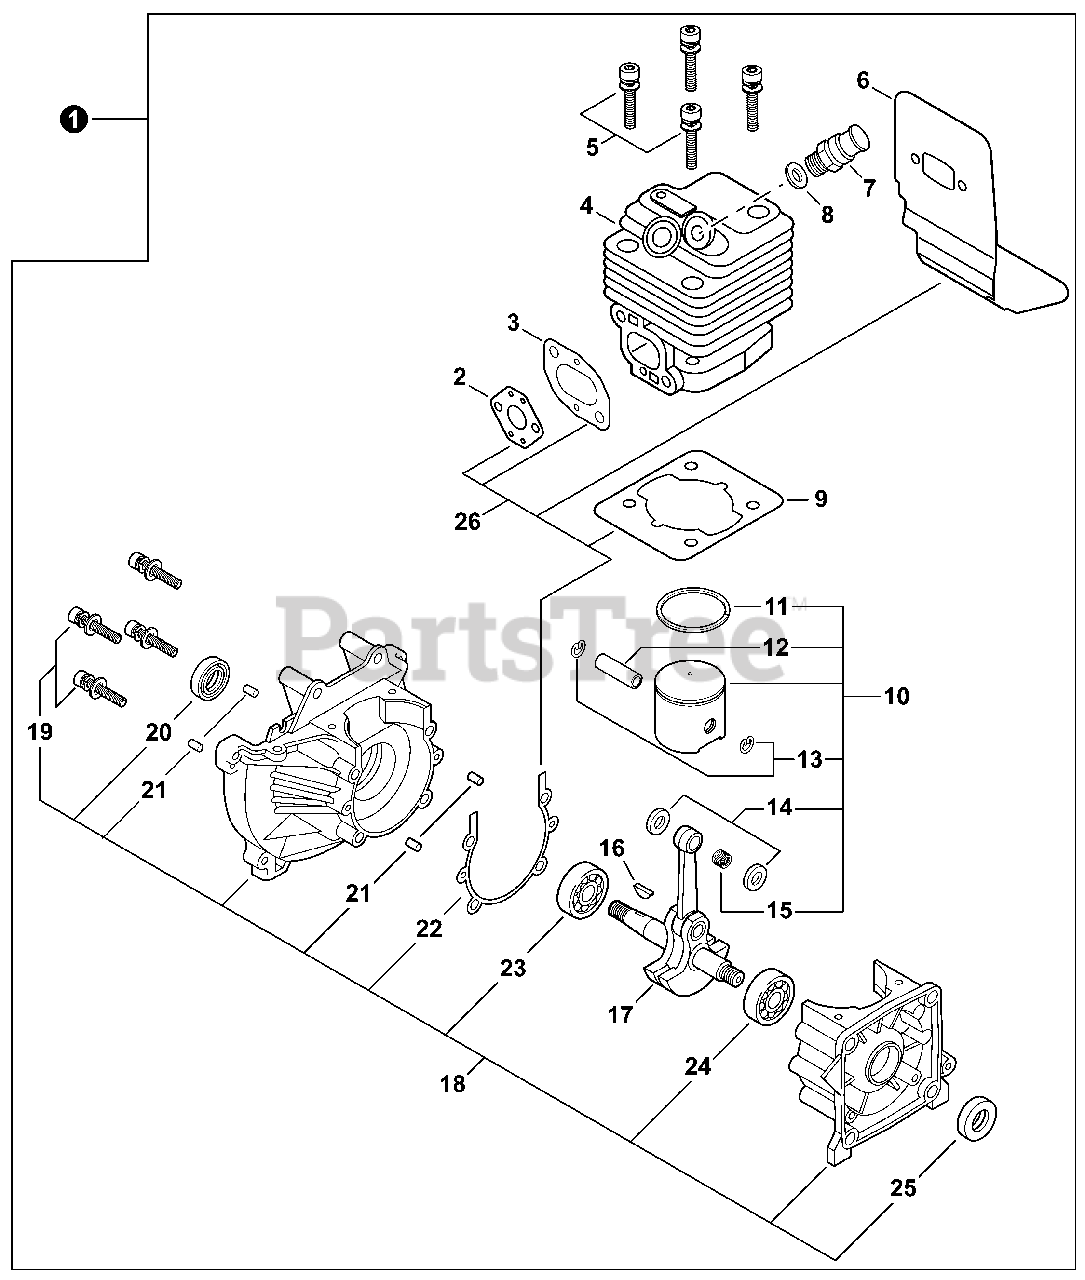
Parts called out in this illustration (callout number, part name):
1	SHORT BLOCK
2	GASKET, INTAKE
3	GASKET, INTAKE
4	CYLINDER
5	BOLT 5×20
6	HEAT SHIELD, EXHAUST
7	VALVE, DECOMPRESSION
8	GASKET, VALVE
9	GASKET, CYLINDER
10	PISTON KIT
11	RING, PISTON
12	PIN, PISTON 10
13	RING, SNAP Ø10
14	WASHER, THRUST
15	BEARING, NEEDLE 10
16	KEY, WOODRUFF 3×14
17	CRANKSHAFT ASSY
18	CRANKCASE KIT
19	BOLT M5×35
20	SEAL, OIL
21	PIN, LOCATING 4×8
22	GASKET, CRANKCASE
23	BEARING, BALL 6202
24	BEARING, BALL - 6201 C3
25	SEAL, OIL 12
26	GASKET KIT
